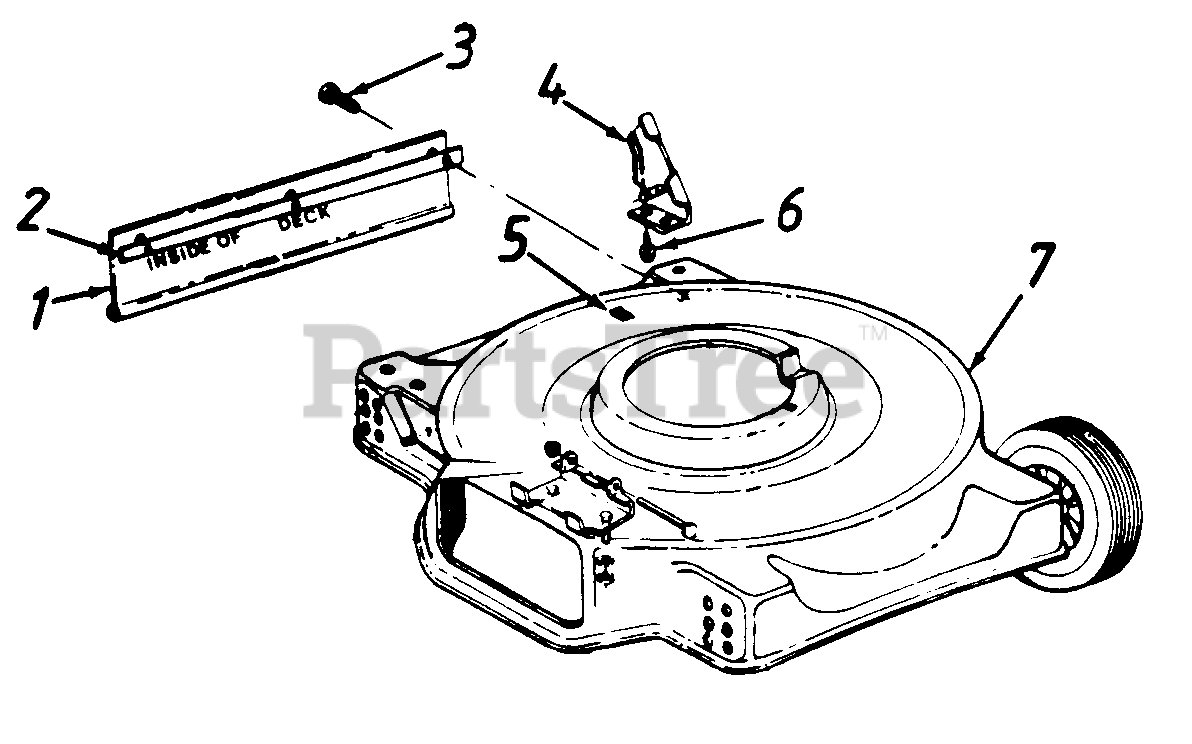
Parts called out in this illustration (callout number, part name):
1	Rear Flap Assemblv
2	Retainer Strip
3	Hex AB-Tap Scr. 1/4" x .62" Lg.
4	Handle Mount Brkt.-L.H.
5	Plastic Plug
6	Hex Sen-Tap Scr. 5/16-18 x .5" Lg.
